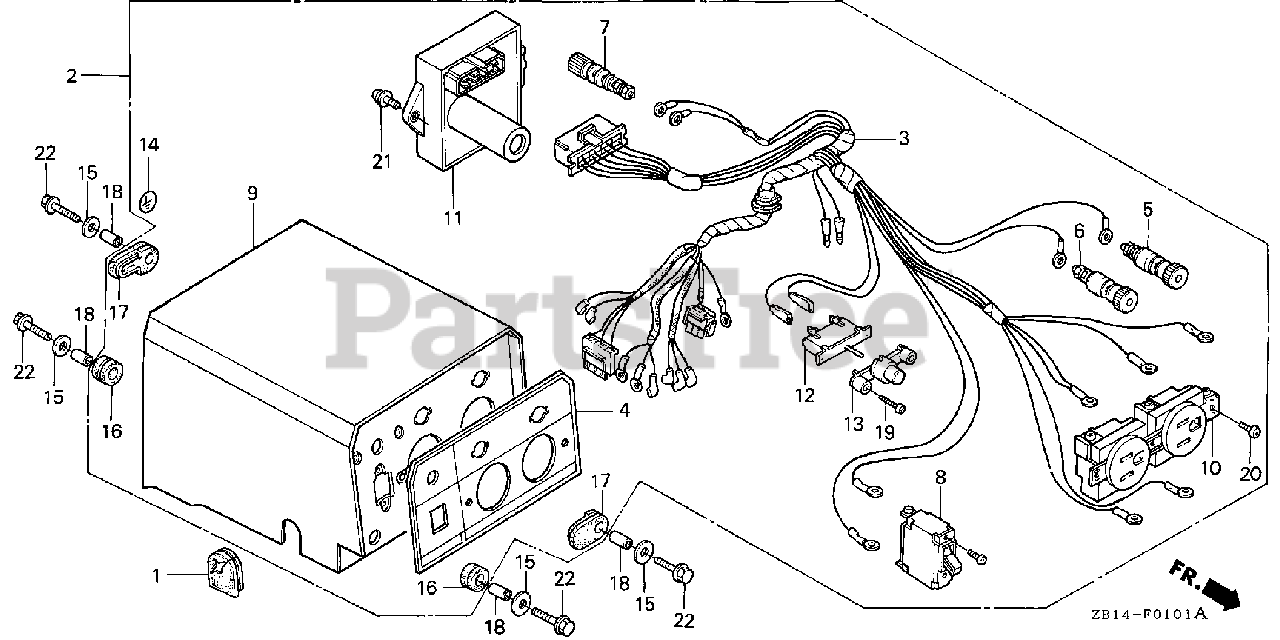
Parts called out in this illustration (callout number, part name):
1	GROMMET, WIRE
2	BOX ASSY., CONTROL
3	WIRE HARNESS ASSY.
4	MARK, SWITCH PANEL (NOT AVAILABLE)
5	TERMINAL, D.C. OUTPUT (+)
6	TERMINAL, D.C. OUTPUT (-)
7	TERMINAL ASSY., GROUND
8	BREAKER, CIRCUIT (17.5A)
9	BOX, CONTROL
10	RECEPTACLE (15A/125V)
11	REGULATOR UNIT, AUTOMATIC
12	PROTECTOR, CIRCUIT (D.C.)
13	LENS ASSY., PROTECTOR
14	MARK, GROUND
15	WASHER, FLAT (20MM)
16	RUBBER, CONTROL BOX
17	RUBBER, CONTROL BOX
18	COLLAR, CONTROL BOX (NA USE ALT:91552-898-000)
19	SCREW, PAN (3X12)
20	SCREW, PAN (4X6)
21	SCREW-WASHER (5X12)
22	BOLT, FLANGE (6X20)
